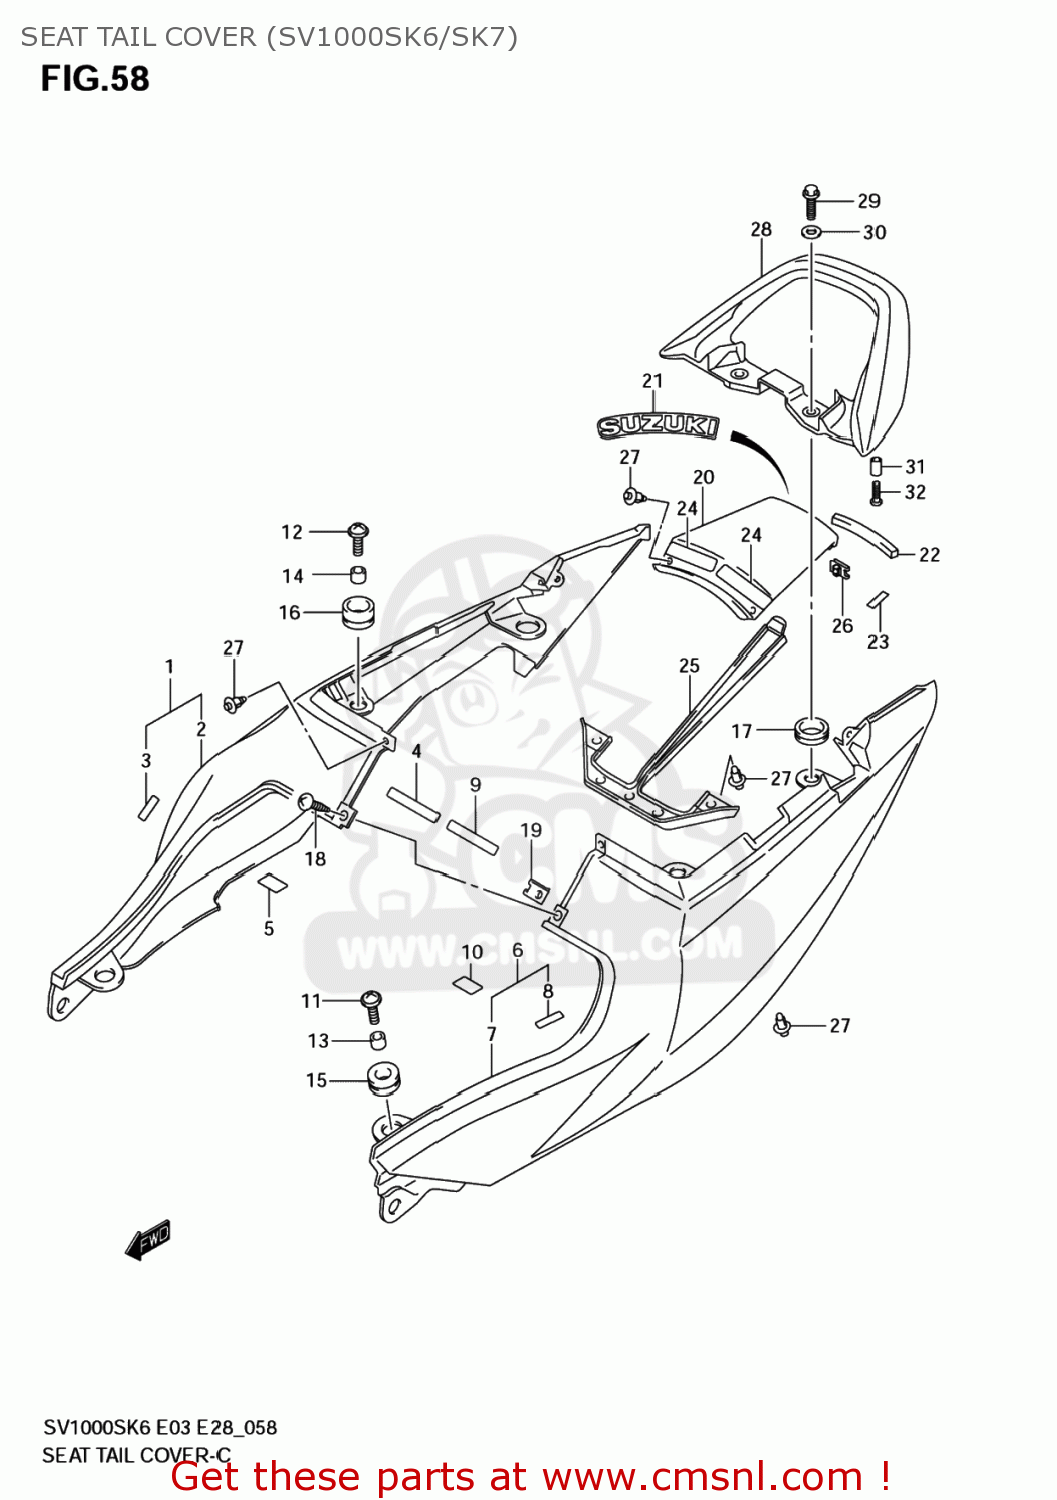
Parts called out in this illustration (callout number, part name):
1	COVER,SEAT TAIL,R(BLUE)
2	COVER,SEAT TAIL,R
3	TAPE,COVER
4	TAPE,SEAT TAIL COVER NO.2 FR
5	PROTECTOR,FRAME COVER
6	COVER,SEAT TAIL,L(BLUE)
7	COVER,SEAT TAIL,L
8	TAPE,COVER
9	TAPE,SEAT TAIL COVER NO.2 FR
10	PROTECTOR,FRAME COVER
11	SCREW(6X25)
12	SCREW(6X25)
13	SPACER(6.5X10X9.4)
14	SPACER(6.5X10X9.4)
15	CUSHION
16	CUSHION,SEAT TAIL COVER CTR
17	CUSHION
18	SCREW
19	NUT
20	COVER,SEAT TAIL CTR
21	EMBLEM,SUZUKI
22	CUSHION,SEAT TAIL COVER CTR
23	TAPE,SEAT TAIL COVER
24	TAPE,COVER
25	COVER,SEAT TAIL RR
26	NUT
27	CLIP(BLACK)
28	HANDLE,PILLION RIDER
29	BOLT
30	WASHER(8.5X24X2.3)
31	SPACER(6.5X9X18)
32	SCREW(6X25)
